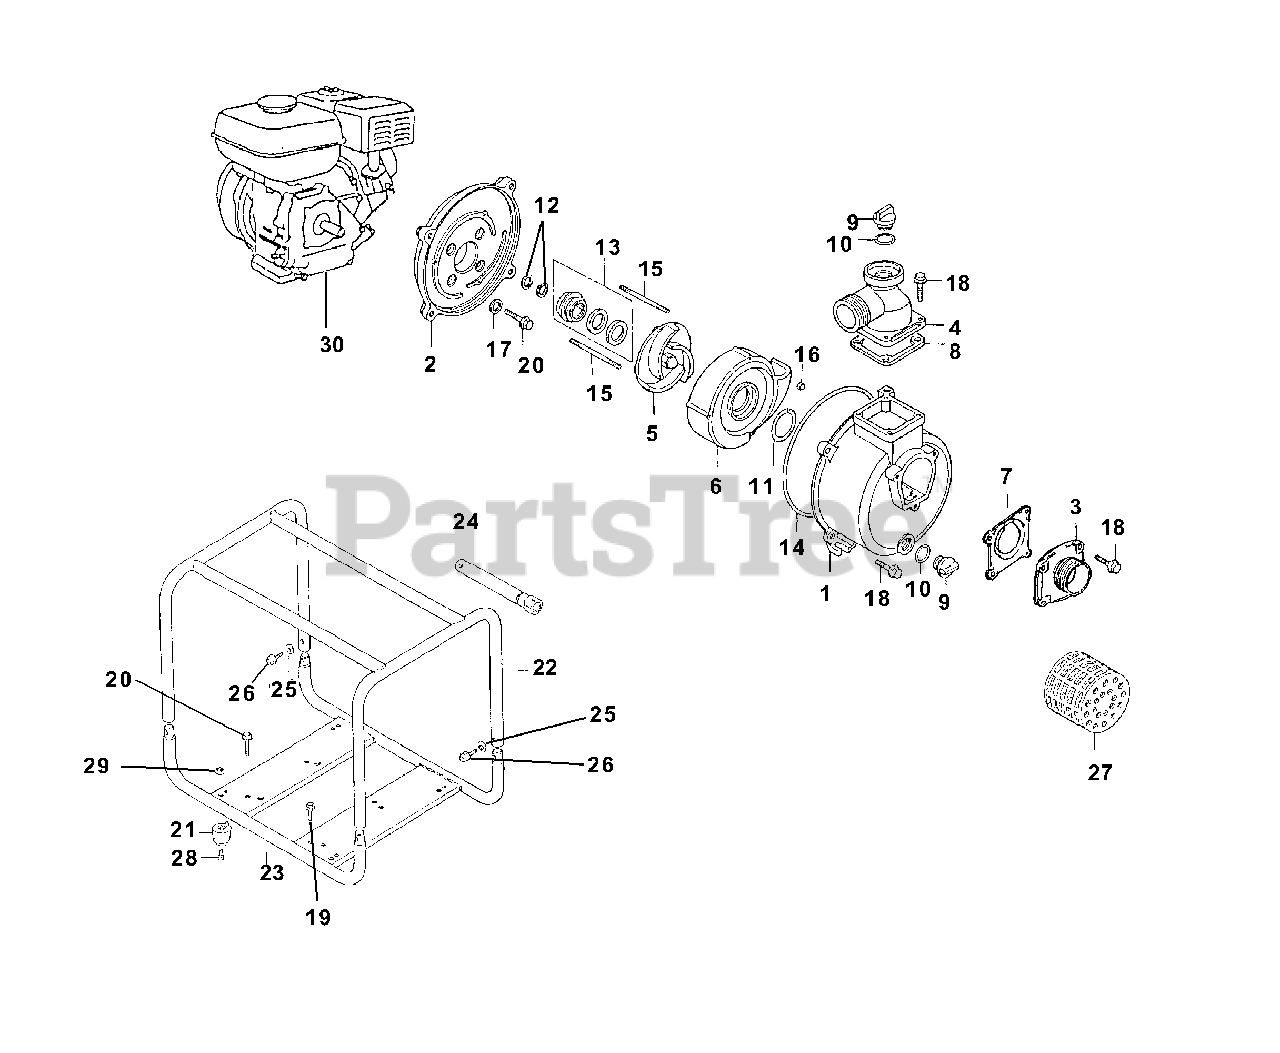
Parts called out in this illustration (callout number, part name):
2	Cover, Casing
3	Inlet Pipe 3" NPT
4	Outlet Pipe 3" NPT
5	Impeller
6	Case, Volute
7	Check Valve, Inlet
8	Packing, Outlet
9	Cap, Filler
10	Ring, Seal
11	O-Ring 71 x 5.7
12	Shim, Adjuster
13	Seal, Mechanical
14	Seal Ring, Casing
15	Stud, Threaded 6 x 50
16	Nut, 6mm
17	Washer, 8mm
18	Bolt, Flanged 10 x 28
19	Bolt, Flanged 8 x 25
20	Bolt, Flanged 8 x 28
21	Foot, Rubber
22	Upper Frame
23	Lower Frame
24	Wrench, Spark Plug
25	Washer, Frame Joint
26	Bolt, Flanged 8 x 18
27	Strainer
28	Screw, Pan Hd. 6 x 10
29	Nut, Hex 6mm
